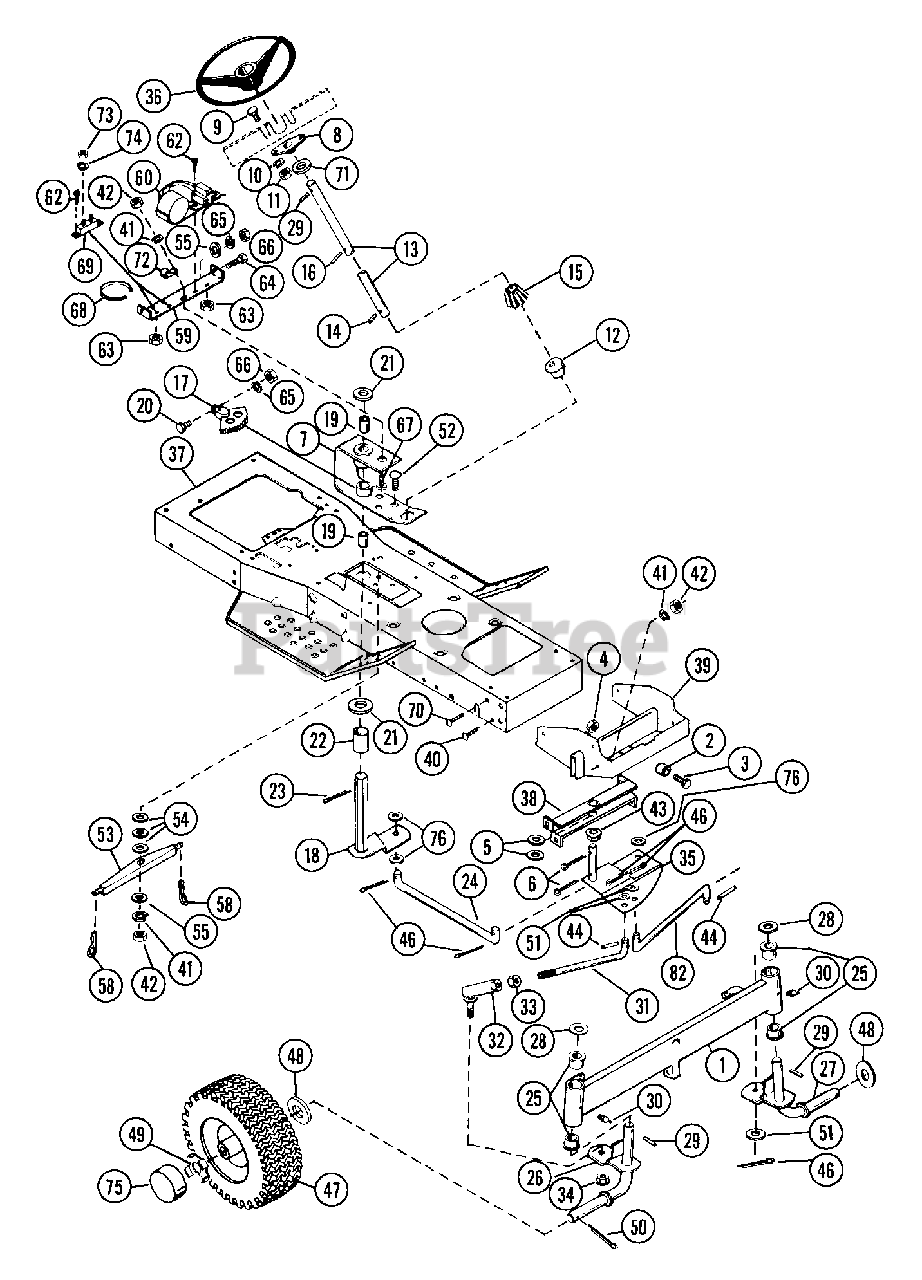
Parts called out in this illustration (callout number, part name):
1	FRONT AXLE WELDMENT
2	SPACER .531X.748X.524
3	BLT-HEX .50-13X1.25 PL GR5
4	NUT-LK-CROWN .50-13 GR C PL
5	WSHR-FL-STL.656X1.312X.095 PL
6	PIN-COTR .12 X 1.25 PL
7	STEERING BRACKET
8	BRG-FLG .751X2 HOLESX.81
9	BLT-HEX .31-18X.75 PL GR5
10	WSHR-LK .312X.097 PL HVY
11	NUT-HEX .312-18
12	BSHG-FLG .750X1.093X.625X1.375
13	STEERING COLUMN
14	PIN .249X1.125 DRIV-LOK SP
15	PINION GEAR-STEERING
16	PIN-ROLL .188X1.13
17	STEERING BEVEL GEAR
18	ARM & SHAFT
19	BSHG-SLV .750X1.000X.750 HX SB
20	BLT-HEX .31-18X1.75 PL GR2
21	WSHR-FL-STL .875X1.250X.075
22	SPACER .780X.900X2.094
23	PIN-COTR .18X1.25 PL
24	STEERING LINK
25	BSHG-FLG .750X1.000X.750X1.250
26	RIGHT SPINDLE WELDMENT
27	LEFT SPINDLE WELDMENT
28	WSHR-FL-STL .755X1.375X.093
29	PIN-ROLL .250X1.25
30	SPIN DRIVE ZERK FITTING
31	DRAG LINK
32	BALL JOINT R.H.
33	NUT-JAM .50-20 PL
34	NUT-LK .50-20 PL
35	STEERING PIVOT
36	STEERING WHEEL
37	MAIN FRAME
38	STEERING PIVOT CHANNEL
39	FRONT AXLE SUPPORT
40	BLT-RDHDSQNK .38-16X.75 SHT PL
41	WSHR-LK .375X.115 HVY PL
42	NUT-HEX .375-16
43	FLANGE BUSHING
44	PIN-ROLL .125X1.00
46	PIN-COTR .12X1.0 PL
47	WHEEL & TIRE ASSEMBLY
47	BRG-BALL .752X1.50X.50
48	WSHR-FL-STL .755X1.375X.093
49	SPINDLE CUP
50	PIN-COTR .25X1.50 ST PL
51	WSHR-FL-STL .520X.827X.062 YZ
52	BLT-RDHDSQNK .38-16X1.25 PL
53	PIVOT ARM
54	WSHR-FL-STL .380X.626X.033
55	WSHR-FL-STL.406X.812X.065PL
58	PIN-HAIR INT .08X.18X1.18
60	MODULE
61	CONNECTOR
62	SCR-MCH 10-24X.62 SLRH PL
63	NUT-KEPS 10-24 PL
64	BLT-HEX .31-18X.75 PL GR5
65	WSHR-LK .312X.097 PL HVY
66	NUT-HEX .312-18
67	BLT-HEX .38-16X1.00 PL
68	TIE DOWN
69	CIRCUIT BREAKER
70	BLT-RDHDSQSHNK .38-16X1.00 PL
71	WSHR-FL-STL .754X1.125X.062 PL
73	NUT 10-32 PL
74	WSHR-LK 10X.047 MED PL
75	HUB CAP
76	WSHR-FL-STL .505X.880X.072 PL
77	WSHR-FL-STL.312X.734X.065PL
78	WSHR-FL-STL .755X1.375X.062 PL
79	PIN-ROLL .250X1.75
80	WSHR-LK .375X.094 MED PL
81	WSHR-FL-STL .880X1.250X.062
82	DRAG LINK
